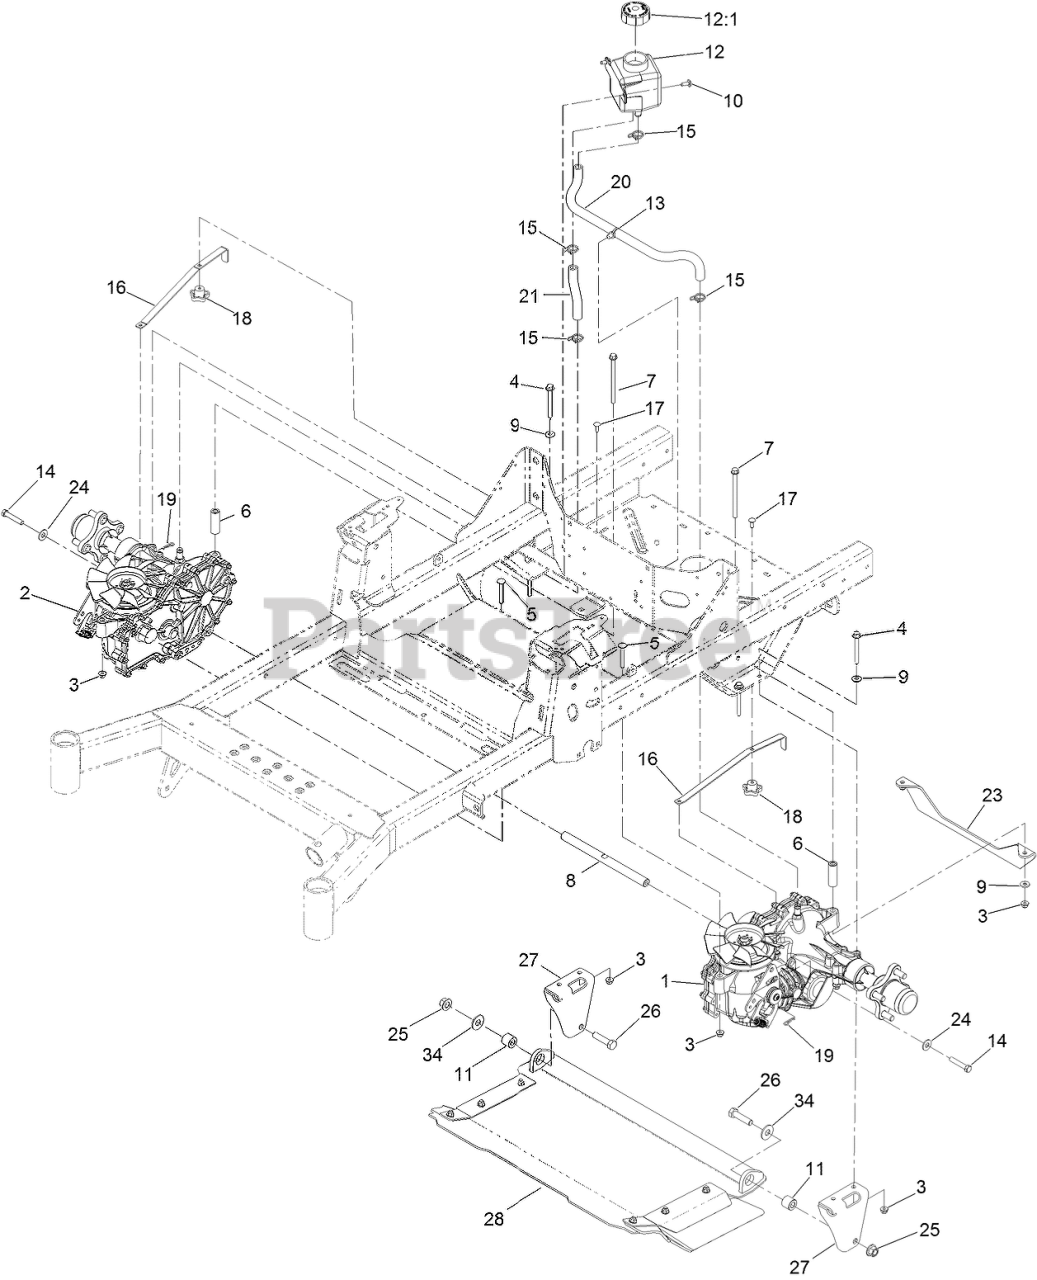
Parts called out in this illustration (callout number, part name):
1	LH TRANSAXLE ASM
2	RH TRANSAXLE ASM
3	NUT-HF, NI
4	SCREW-HHF
5	BOLT-CARR
6	SPACER-HYDRO
7	SCREW HHF
8	SHAFT-SPACER
9	WASHER-SPRING
10	SCREW-TORX
11	BUSHING-SLEEVE
12	TANK-HYD
12:1	CAP-RESERVOIR, HYD
13	CLIP-TIE
14	SCREW-HH W/LOCTITE
15	CLAMP-HOSE
16	ARM-BYPASS, HYDRO
17	BOLT-CARR
18	KNOB-HANDLE
19	PIN-COTTER
20	HOSE-HYDRAULIC
21	HOSE-HYDRAULIC
23	SUPPORT-TRANSMISSION
24	WASHER-FLAT
25	Nut-Lock 1/2-13
26	SCREW-HH
27	BRACKET-MOUNT, DISCHARGE
28	DISCHARGE TUNNEL ASM
34	WASHER-FLAT
